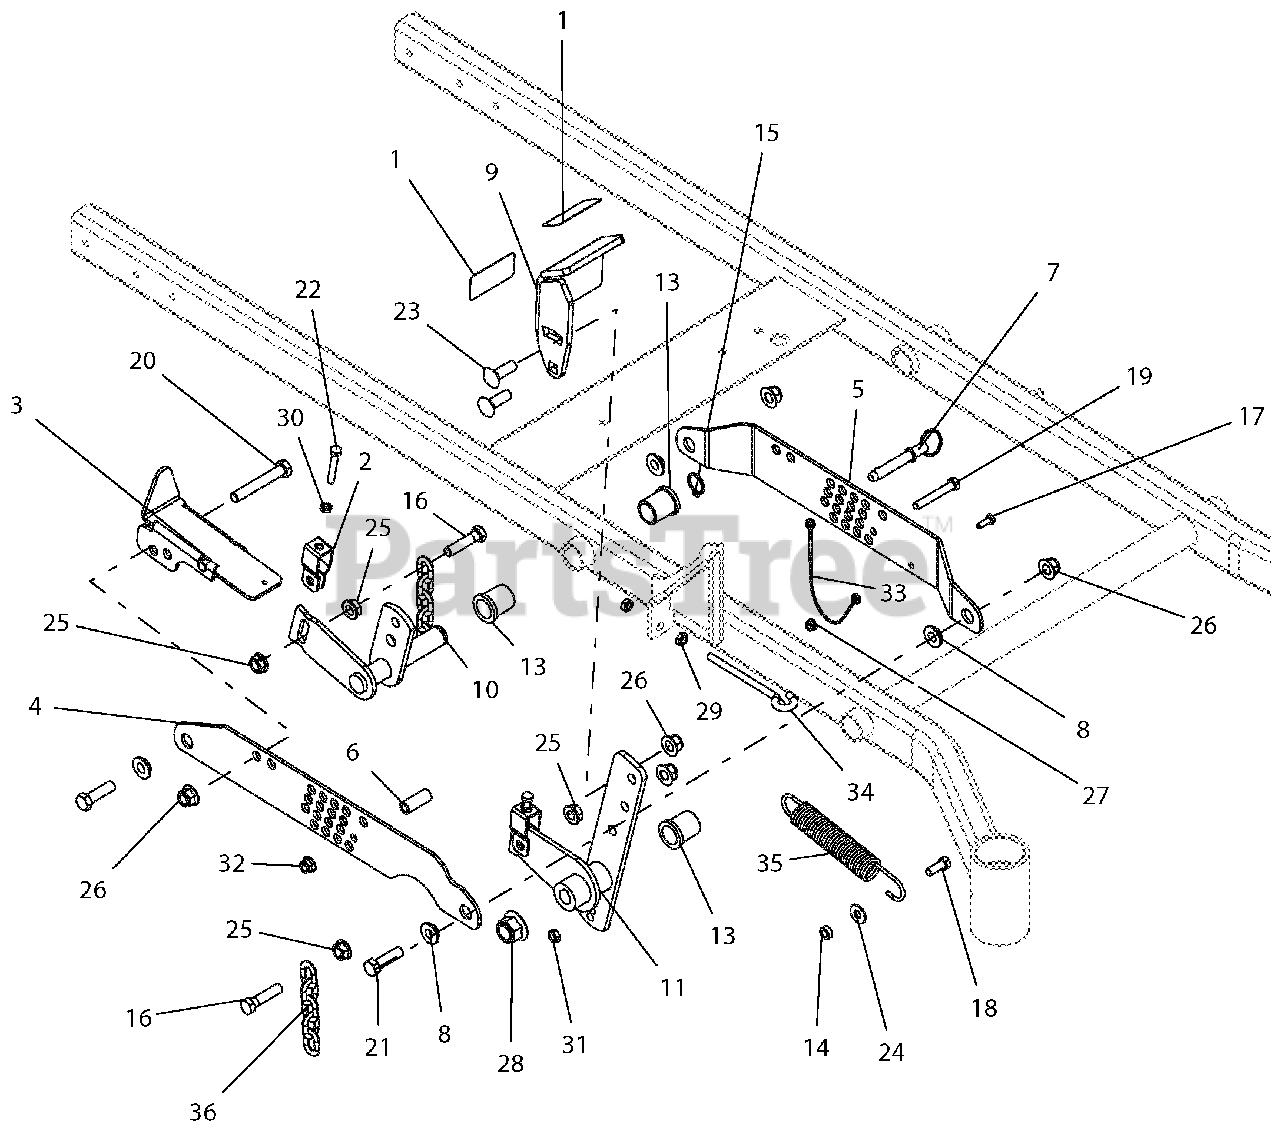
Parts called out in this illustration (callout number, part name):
1	GRIP, PEDAL 1.50 X 3.00
2	BRKT, DECK LEVELING
3	WLDMT, MECHANICAL LOCK-UP-BLACK
4	BRKT, RH OUTBOARD LIFT/CUT HEIGHT-BLACK
5	BRKT, RH INBOARD LIFT/CUT HEIGHT-BLACK
6	SPACER, .375 X .625 X 1.54
7	PIN, .50 X 2.00 USABLE LG BALL
8	BSHG, FLANGE .515X.750X.31X1.12
9	PEDAL, ADJUSTABLE FOOT LIFT-BLACK
10	WLDMT, REAR RH DECK LIFT
11	WLDMT, PT FRONT RH DECK LIFT ARM-BLACK
13	BSHG-FLG 1.00X1.25X1.5X1.5
14	BSHG, SLV .377X.624X.235
15	RG-RTNG-EXT 1.00X.078
16	BLT, HEX M12-1.75X50 CLS8.8 YZ
17	BLT-HEX .25-20X.75 GR5 YWZC
18	BLT-HEX .38-16X1.00 GR5 YWZC
19	BLT-HEX .38-16X2.50 GR5 YWZC
20	BLT-HEX .50-13X3.25 GR5 YWZC
21	BLT-HEX .50-13X1.75 GR5 YWZC
22	BLT-HEX .31-18X2.00 FTH GR5 YWZC
23	BLT-RDHDSQNK .50-13X1.50 G5 YWZC
24	WSHR-FL-STL.438X1.00X.083 YWZC
25	NUT, SPLK -FLG M12-1.75 YZ
26	NUT-LK-NYL-FLG .50-13 YWZC
27	NUT-LK-NYL-FLG .25-20 YWZC
28	NUT-LK-NYL-FLG .75-10 YWZC
29	NUT, JAM .375-16 YWZC
30	NUT, JAM .312-18 YWZC
31	@NUT-LK-CTR-JAM .375-16 YWZC
32	NUT-LK-NYL-FLG .38-16 YWZC
33	LANYARD, 12"
34	BOLT, EYE .38-16X6.00 .62 DIA
35	SPRG, TENSION .162 X 1.250 X 8.250
36	CHAIN, MOWER LIFT
